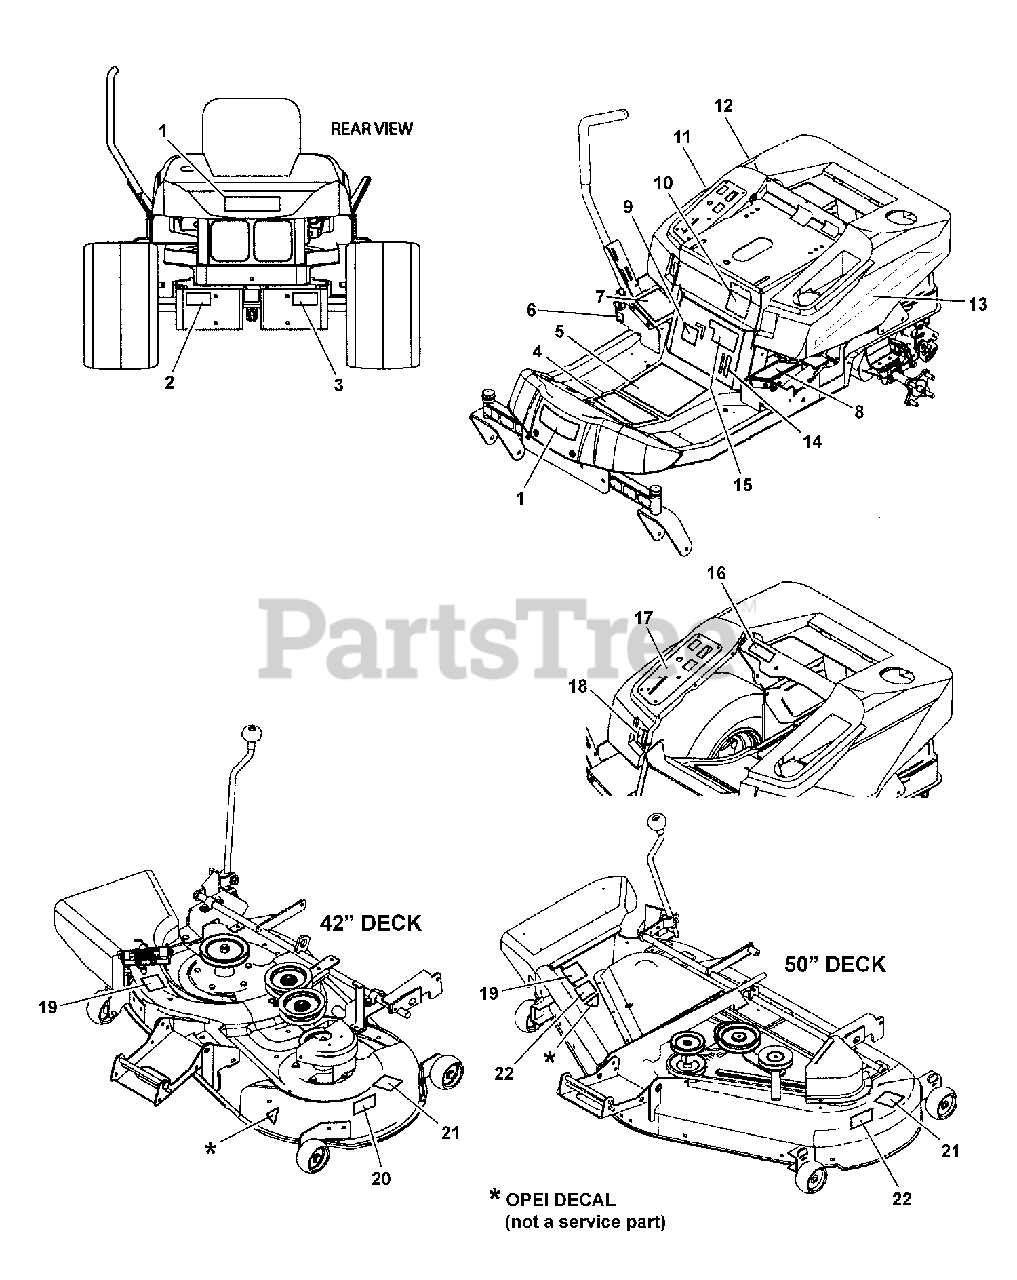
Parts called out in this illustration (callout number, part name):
1	DECAL, SNAPPER Logo
2	DECAL, Caution Cut Hazard
3	DECAL, Transmission Release ZTS Export
4	DECAL, Handles Operation
5	DECAL, Operator Instructions
6	DECAL, Tracking Adjustment ZT 7000
7	DECAL, RH Handle
8	DECAL- LH Handle Control ZTS 7500
9	DECAL, Parking Brake, ZT
10	DECAL, Belt/Blade ZT
11	DECAL, Hot Surfaces
12	DECAL, New Snapper Stripe, RH
13	DECAL, New Snapper Stripe, LH
14	DECAL, Height-Of-Cut
15	DECAL, 150Z 21HP SNAPPER ZT
15	DECAL, 150Z 24HP SNAPPER ZT
16	DECAL, Do Not Remove Foam Around Engine
17	DECAL, Instrument Panel, ZTS 7500
18	DECAL, Mower Cutting Height ZTS 7500
19	DECAL, Danger Do Not Operate w/o Deflector
20	DECAL, 42" 2006 Silver/Black
21	DECAL, Danger Do Not Put Hands/Feet in Mower
22	DECAL, 50" Silver on Black w/Stripe
